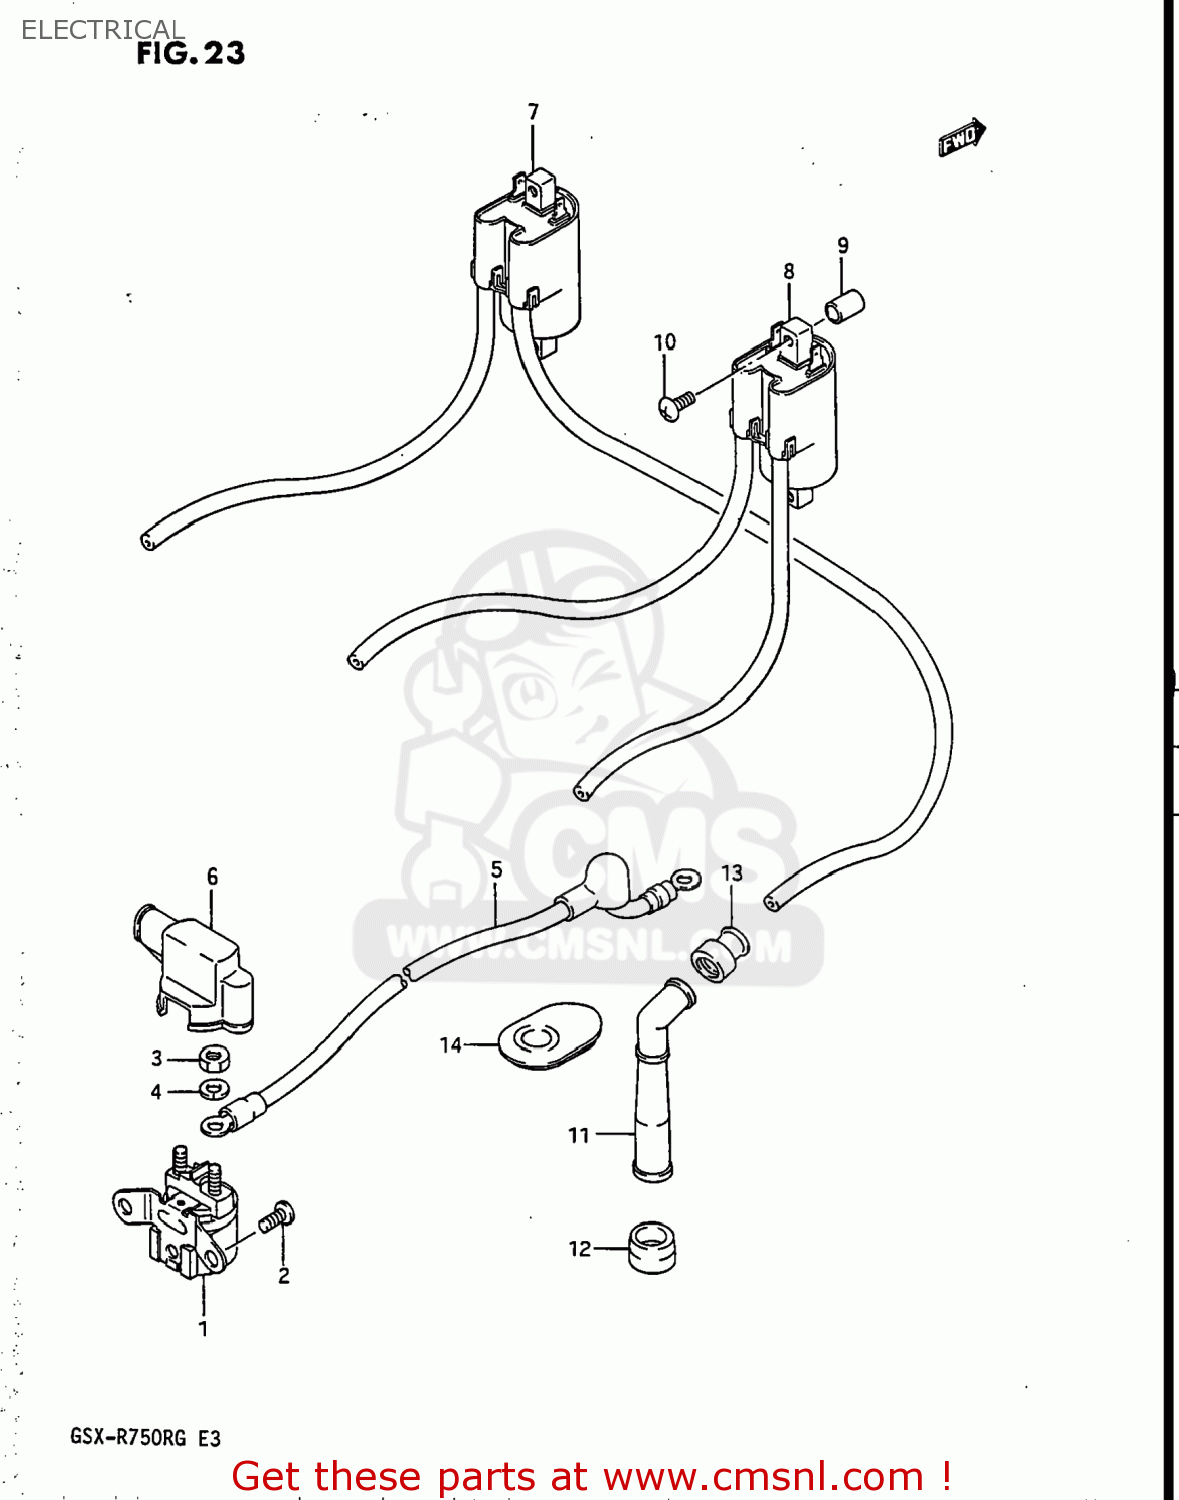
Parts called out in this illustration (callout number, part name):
1	RELAY ASSY,STARTING MOTOR
2	SCREW
3	NUT
4	WASHER,LOCK
5	WIRE,STARTER MOTOR LEAD
6	CAP,STARTER RELAY
7	COIL ASSEMBLY,IGNITION
8	COIL ASSEMBLY,IGNITION
9	SPACER
10	SCREW
11	CAP,SPARK PLUG
12	SEAL,SPARK PLUG
13	SEAL,SPARK PLU
14	COVER,SPARK PLUG CAP
